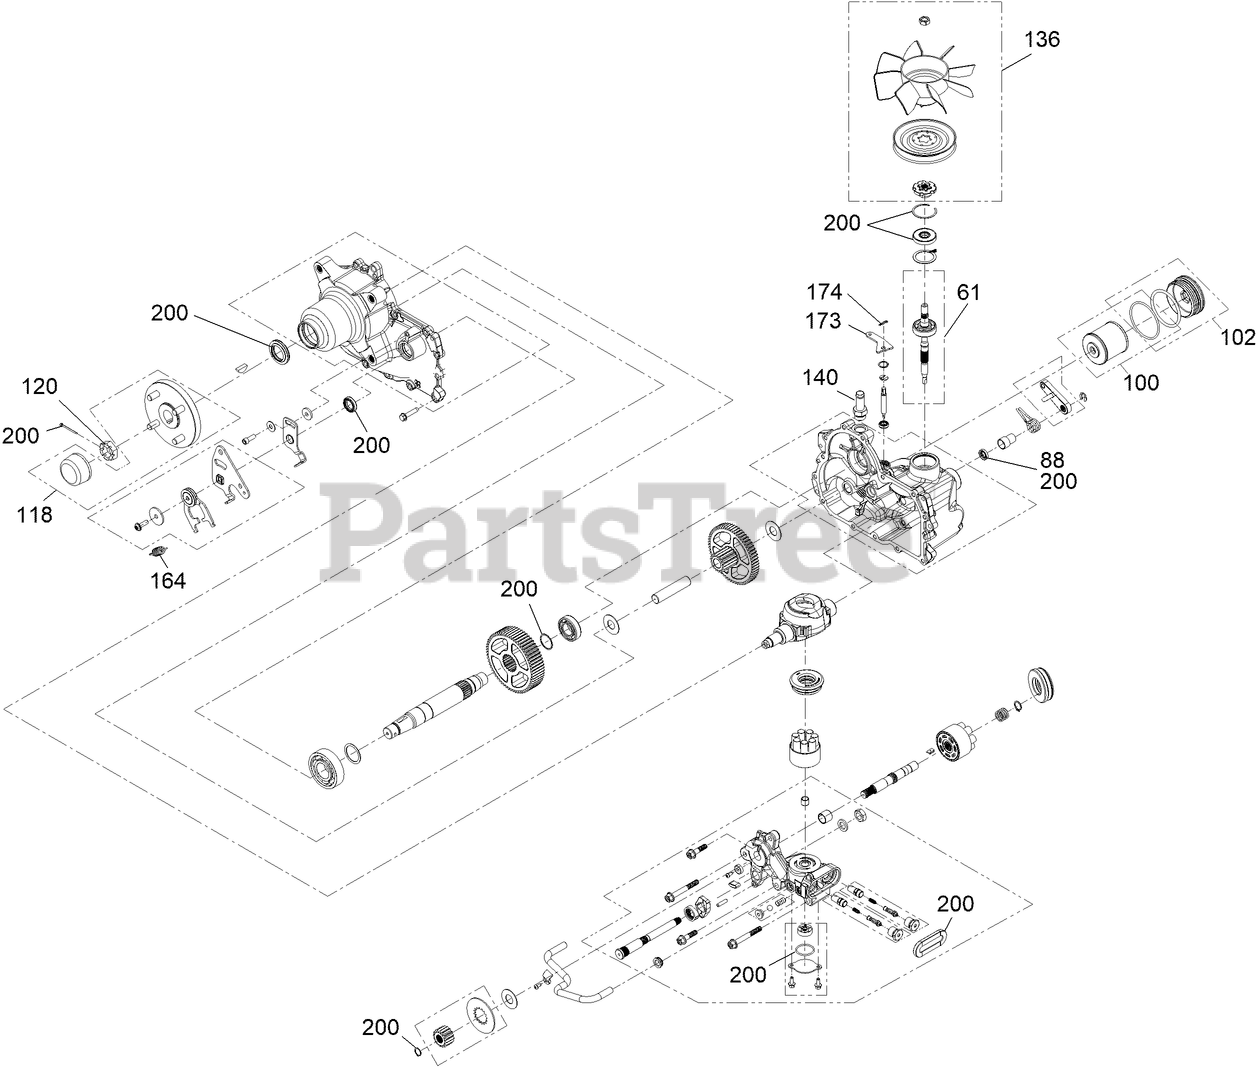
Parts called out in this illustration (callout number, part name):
61	Kit, Input Shaft
88	Seal, Brake
100	Kit, Filter
102	Kit, Filler Cap
118	HUB-4 BOLT
120	NUT, SLOTTED
136	KIT, FAN AND PULLEY
140	Fitting-5/8 Beaded, 7/8 SAE
164	SPRING-EXTENSION
173	Plate-Lever, Bypass
174	PIN-COTTER, LOCKING
200	Kit-Seal
